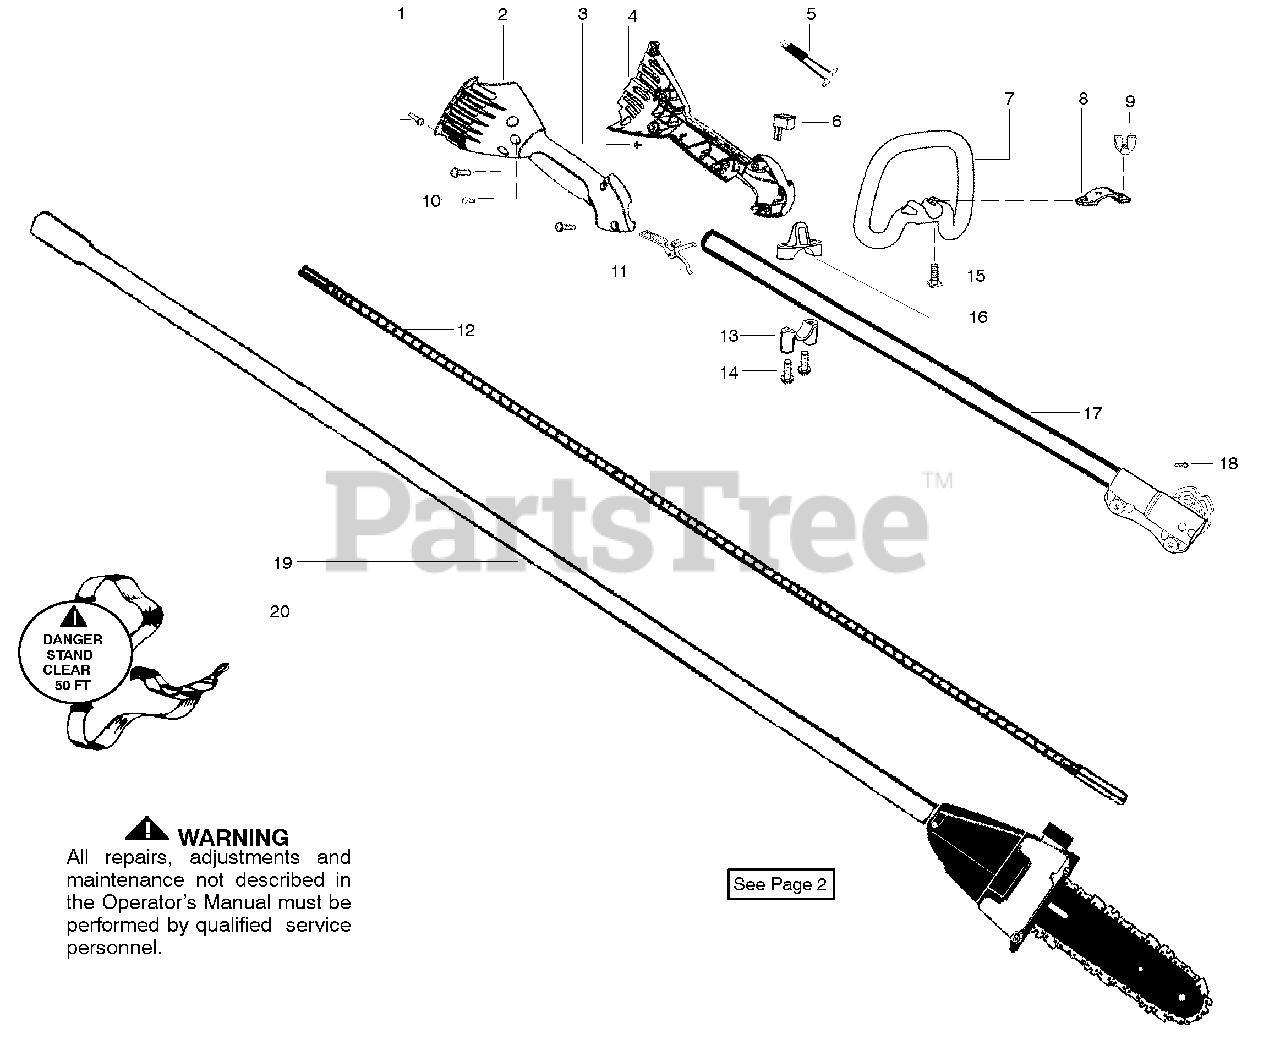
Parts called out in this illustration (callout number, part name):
2	Hsg.-Throttle right
3	Screw-Cable Ret.
4	Hsg.-Throttle left
7	Handle-Assist
9	Wingnut
10	Screw-Align
11	Trigger-Throttle
17	Kit-Upper Shaft
19	Assy-Driveshaft
20	Assy-Shoulder Strap
